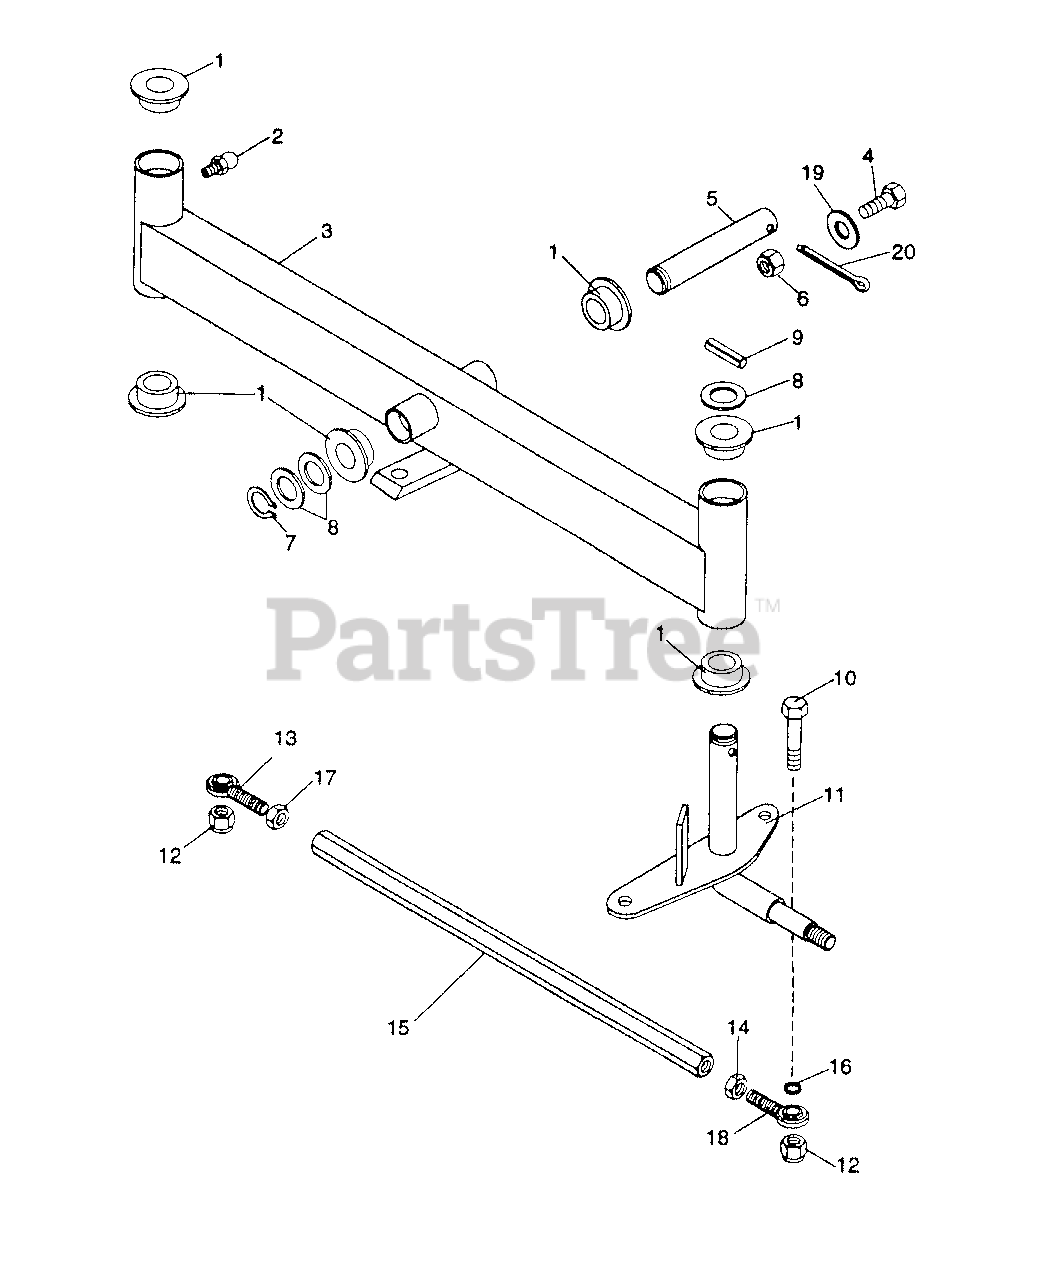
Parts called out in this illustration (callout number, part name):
1	BSHG-FLG 1.020 X 1.385 X .75 X 1.75 NY
2	FTG, LUBE; .25-28 SELF THREAD
3	WLDMT, AXLE
4	BLT-HEX .25-20 X .875
5	SHAFT, PIVOT
6	NUT-LK-NYL .250-20 PL
7	RG-RTNG-EXT .906 X .078
8	BRG-R-THRST 1.002 X 1.552 X .030
9	PIN-ROLL .250 X 1.50
10	BLT-HEX .50-13 X 2.00 PL GR 5
11	WLDMT, KINGPIN L.H.
11	WLDMT, KINGPIN R.H.
12	NUT-LK-NYL .50-13 PL
13	ASM, ROD ENDR.H.
14	NUT-JAM .50-20 PL
15	ROD, TIE
16	WSHR-FL-STL .531 X 1.062 X .095
17	NUT-JAM .50-20 LH THD PL
18	ASM, ROD ENDL.H.
